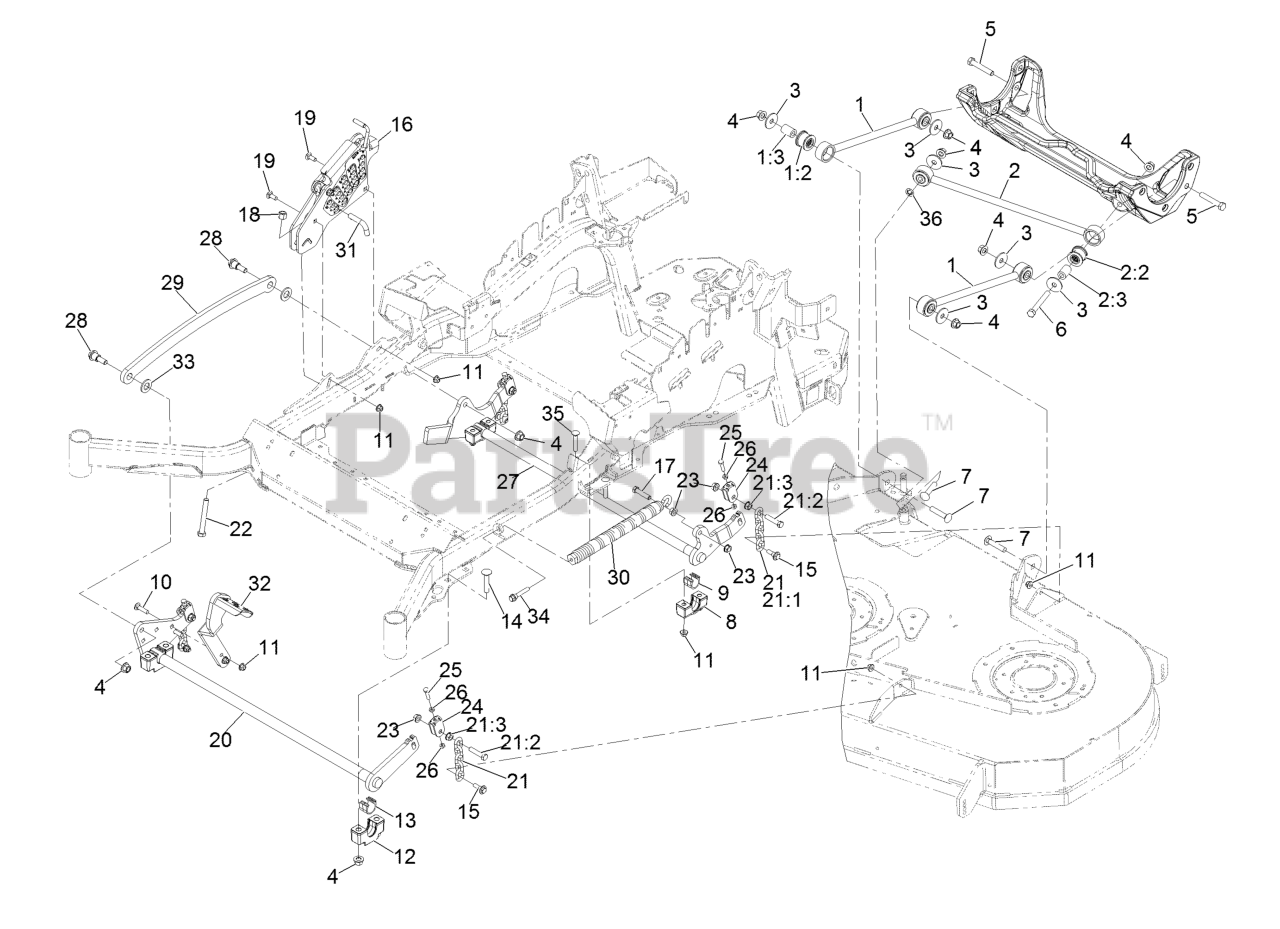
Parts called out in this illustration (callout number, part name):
1	Deck Strut ASM
1:2	Bushing-Suspension, Rubber
2	Panhard Rod ASM
2:2	Bushing-Suspension, Rubber
4	Nut-Lock 1/2-13
5	Screw-HH 1/2-13 X 3
6	Screw-HH 1/2-13 X 4
7	Bolt-Carriage 1/2-13 X 2 1/2
8	Support-Cross Shaft, Bearing Rear
9	Bearing-Cross Shaft, Rear
10	Bolt-Carriage 3/8-16 X 1 1/2
11	Nut-Nyloc 3/8-16 Flg
12	Support-Cross Shaft, Bearing
13	Bearing-Cross Shaft, Front
14	Bolt-Carriage 1/2-13 X 2 1/2 Spl Neck
15	Screw-Hex Flange 3/8-16 X .80
16	HOC ASM
17	Screw-HH 7/16-14 X 2
18	Nut-Nyloc 1/2-13
19	Bolt-Carriage 3/8-16 X 1
20	Decklift-Front
21	Deck Lift Chain ASM
21:1	Chain-Lift, Deck
21:2	Screw-HH 7/16-14 X 2
21:3	Nut-Whizlock 7/16-14
22	Bolt-HH 1/2-13 X 4 Tap
23	Nut-Whizlock 7/16-14
24	Yoke-Adjust, Deck
25	Screw-HH 5/16-18 X 1 1/4
26	Nut-Jam 5/16-18
27	Lift-Deck, Rear
28	Screw-Shoulder HHF 1/2-13 X 1.12
29	Link-Lift, Deck
30	Spring-Extension
31	Pin-HOC
32	Lever-Foot
33	Washer-3/4 SAE
34	Screw-Shcs 3/8-16 X 2.212
35	Bolt-Carriage 3/8-16 X 2 1/4
36	Nut-Push
